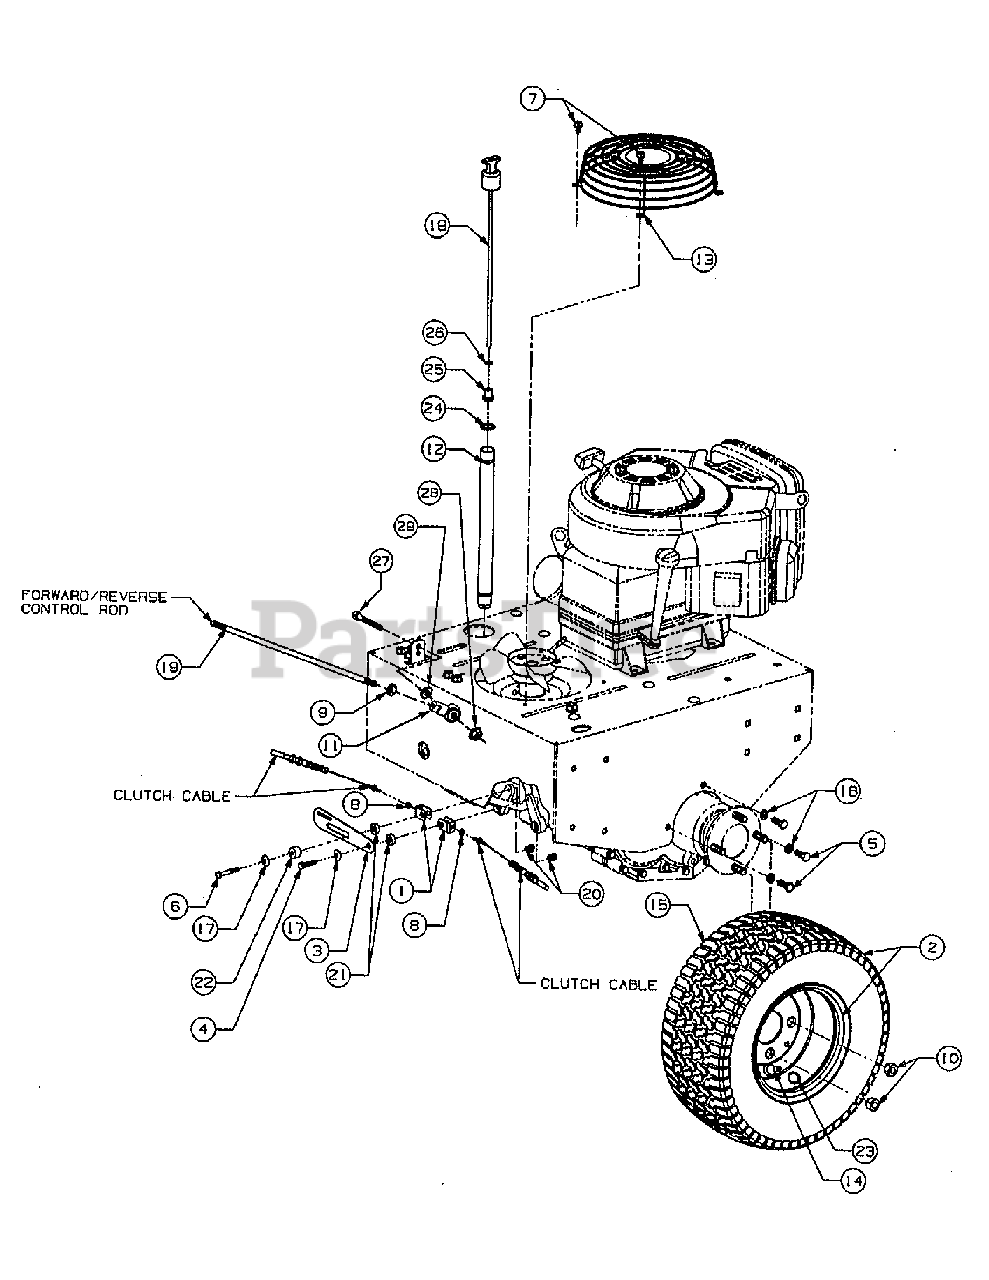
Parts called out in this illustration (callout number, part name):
1	U-Clevis, Clutch Cable
2	Wheel & Tire Assembly, Complete 16 x 7.5-8
3	Plate, Parking Brake Switch Mount
4	Screw, Hex Cap, 1/4-28 x 1.25 Gr 5
5	Screw, Hex Cap, 3/8-16 x 1.0 Gr 5
6	Screw, Hex Cap, 1/4-28 x 1.75 Gr 5
7	Screw, Hex Wash Hd Tapp, 5/16-18 x .50
8	Nut, Hex Jam, #10-32
9	Nut, Hex Jam, 3/8-24 Gr 5
10	Nut, Lug, 1/2-20
11	Rod End, Spherical
12	Tube, Oil Fill
13	Guard, Fan Cover
14	Valve, Tubeless Air
15	Tire, Turf Chief, 16 x 7.5-8
16	Washer, Lock 3/8
17	Washer, Bell, .265 x .75 x .062 Thk
19	Rod, F/R Control
20	Nut, Clevis Spacer, 1/4-28
21	Spacer, Clevis
22	Spacer, Switch Engagement
23	Label, Inflation
25	Seal, Rubber
26	Washer, Plain 5/16
27	Screw, Hex Cap, 3/8-16 x 1.25
28	Nut, Flanged Lock, 3/8-16
29	Washer, Flat .407 x .812 x.135 HDN
